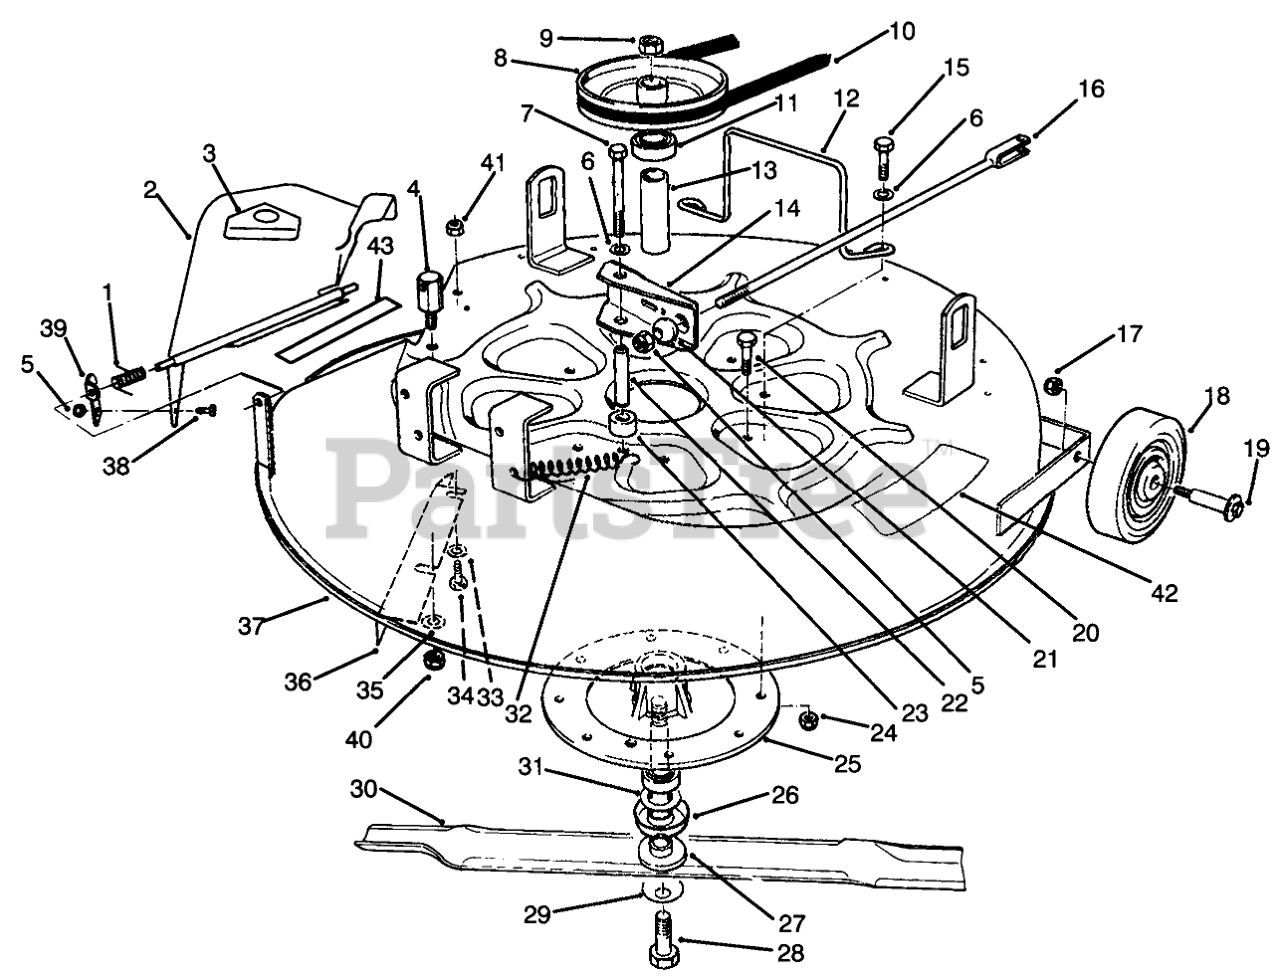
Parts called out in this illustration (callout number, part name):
1	SPRING
2	Deflector(Incl. Ref. #3)
3	DECAL-DANGER
4	POST-PIVOT
5	NUT-HEX
6	WASHER-PLAIN
7	SCREW-HH
8	PULLEY-DECK
9	NUT-HEX
10	V-Belt
11	BEARING-BALL
12	GUIDE-DECK BELT
13	SPACER-BEARING
14	DECK BRAKE ASSEMBLY
15	SCREW-HH
16	DECK BRAKE ROD WA
17	NUT-LOCK, NI
18	WHEEL-DECK
19	BOLT-WHEEL
20	SCREW-HH
21	BALL-SWIVEL, STOP
22	POST-BRAKE MTG
23	SPACER-DECK BRAKE
24	NUT-LOCK, NI
25	CASTING-SPINDLE
26	SHIELD-BEARING
27	SHAFT-SPINDLE
28	SCREW-HH
29	WASHER-BELLEVILLE
30	Blade
31	SPACER
32	SPRING-EXTENSION
33	WASHER-FLAT
34	SCREW-HHF
35	WASHER-FLAT
36	BAFFLE PLATE RED
37	Deck (Incl. Ref. #42)
38	SCREW-HH
39	Bracket-Detector
40	NUT-LOCK, NI
41	NUT-LOCK, NI
42	DECAL - DANGER
43	DECAL-DANGER, DEFLECTOR
